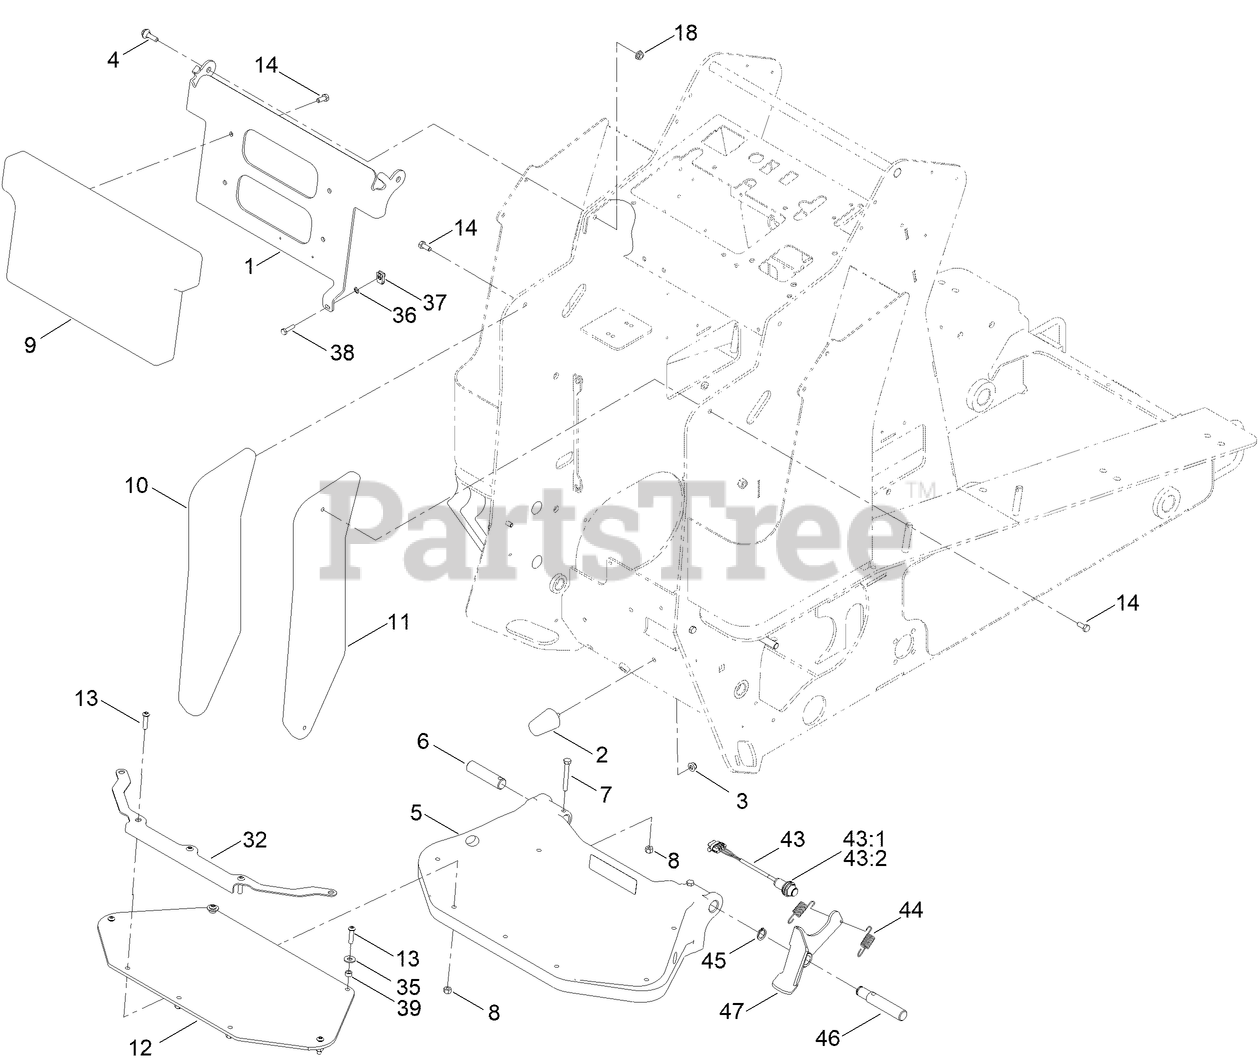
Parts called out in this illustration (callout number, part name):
1	HINGE-PAD
2	BUMPER
3	NUT-HF, NI
4	SCREW-SHOULDER
5	PLATFORM
6	PIN-PIVOT
7	SCREW-HH
8	NUT-LOCK, NI
9	CUSHION-PAD
10	CUSHION-PAD
11	CUSHION-PAD
12	PAD-FOOT
13	SCREW-HSBH
14	SCREW-HH
18	NUT-HF
32	PLATE-CLAMP
35	WASHER-FLAT
36	NUT-RETAINING
38	SCREW-HH
39	SPACER-PIVOT, TILT
43	PROXIMITY SWITCH ASM
43:1	NUT-HEX
43:2	WASHER-LOCK, INTERNAL TOOTH
44	SPRING-EXTENSION
45	RING-RETAINING
46	PIN-PLATFORM
47	PEDAL ASM
